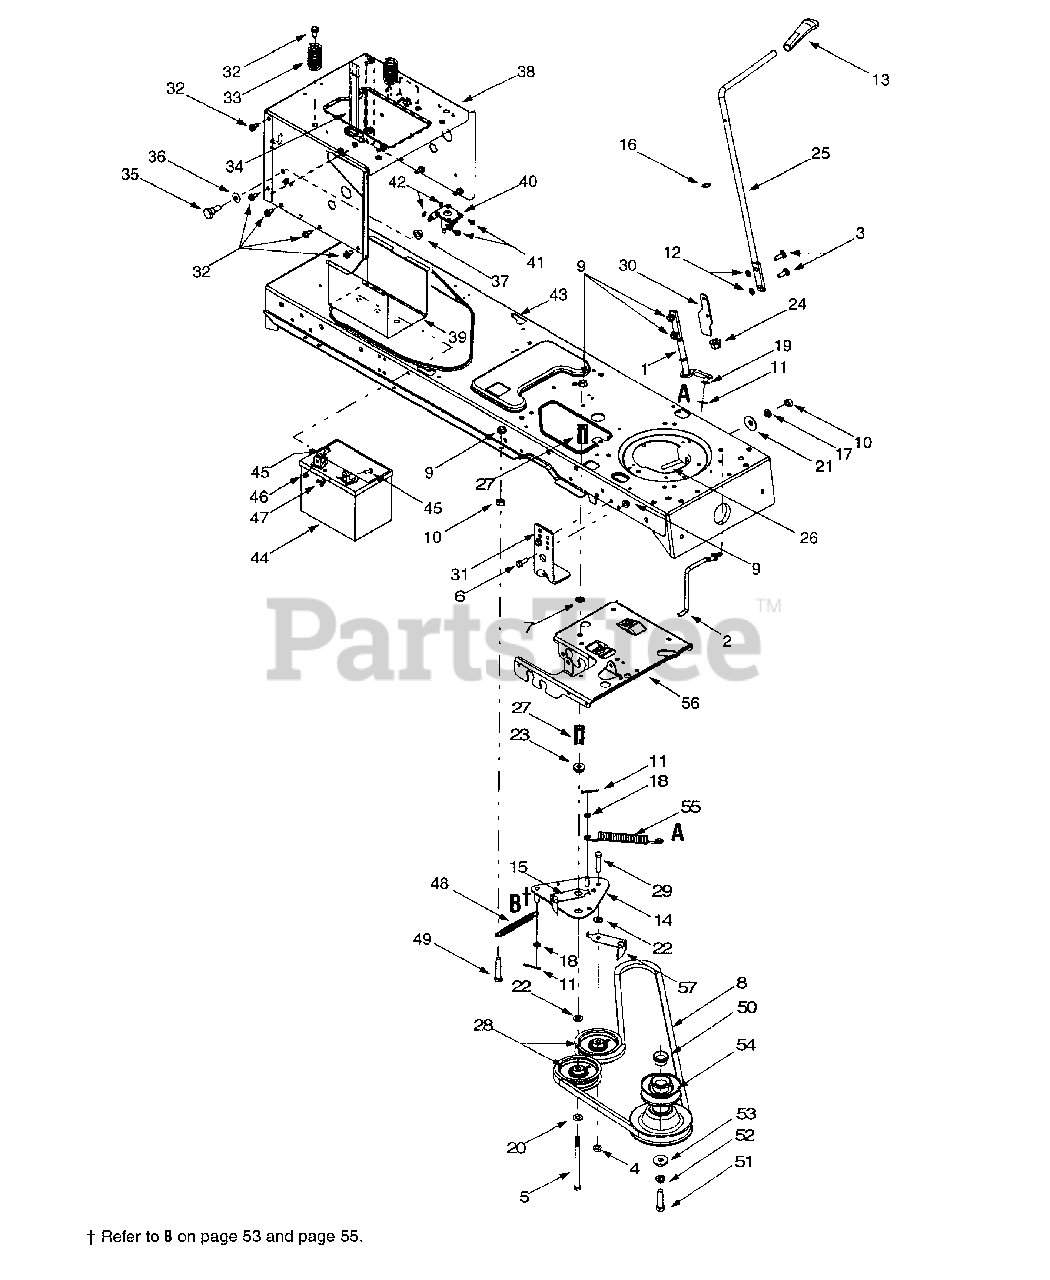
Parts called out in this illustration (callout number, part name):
1	PTO Engage Lever Assembly
2	Belt Keeper Rod
3	Carriage Screw, 5/16-18 x 1.00
4	Flange Lock Nut, 3/8-16
5	Hex Cap Screw, 3/8-16 x 5.5
6	Hex Head Washer Screw, 5/16-18 x .87
7	Push Nut, 3/8
8	PTO Belt
9	Flange Lock Nut, 5/16-18
10	Hex Nut, 5/16-18
11	Cotter Pin, 1/8 x 1.25
12	Speed Nut, .3125
13	PTO Knob
15	Belt Guard
16	Flat Washer, .510 x .750 x .033
17	Lock Washer, 5/16
18	Flat Washer, .385 x .62 x .063
19	Flat Washer, 5/16
20	Flat Washer, .406 x .875 x .059
21	Bell Washer, .39 x 1.13 x .062
22	Flat Washer, .407 x .812 x .135
23	Shoulder Spacer, .380
24	Hex Split Flange Bearing, .5
26	Belt Keeper Rod
27	Spacer, 3/8 x 1.54
28	Idler Pulley, 3.5
29	Hex Cap Screw, 3/8-16 -x 1.75
32	Self Tapping Screw, 5/16-18 x .625
33	Compression Spring, 1.28 x 3.5
34	Battery Strap
35	Shoulder Screw, .625 x .5, 7/16-20
36	Bell Washer, .45 x 1.0 x .062
37	Flange Lock Nut, 7/16-20
41	Self Tapping Screw, 1/4-20 x.5
42	Lock Washer, 1/4
45	Hex Cap Screw, 1/4-20 x .62
46	Hex Sems Nut, 1/4-20
47	Wing Nut, 1/4-20
48	Extension Spring, .50 x 5.0
49	Hex Cap Screw, 5/16-18 x 1.75
50	Spacer Cup
51	Hex Head Cap Screw, 7/16-20 x 1.25
52	Lock Washer, 7/16
53	Flat Washer, .450 x 1.25
54	Engine Pulley, 3.56 OD x 5.56
55	Extension Spring, .75 x 6.75
57	Belt Guard
